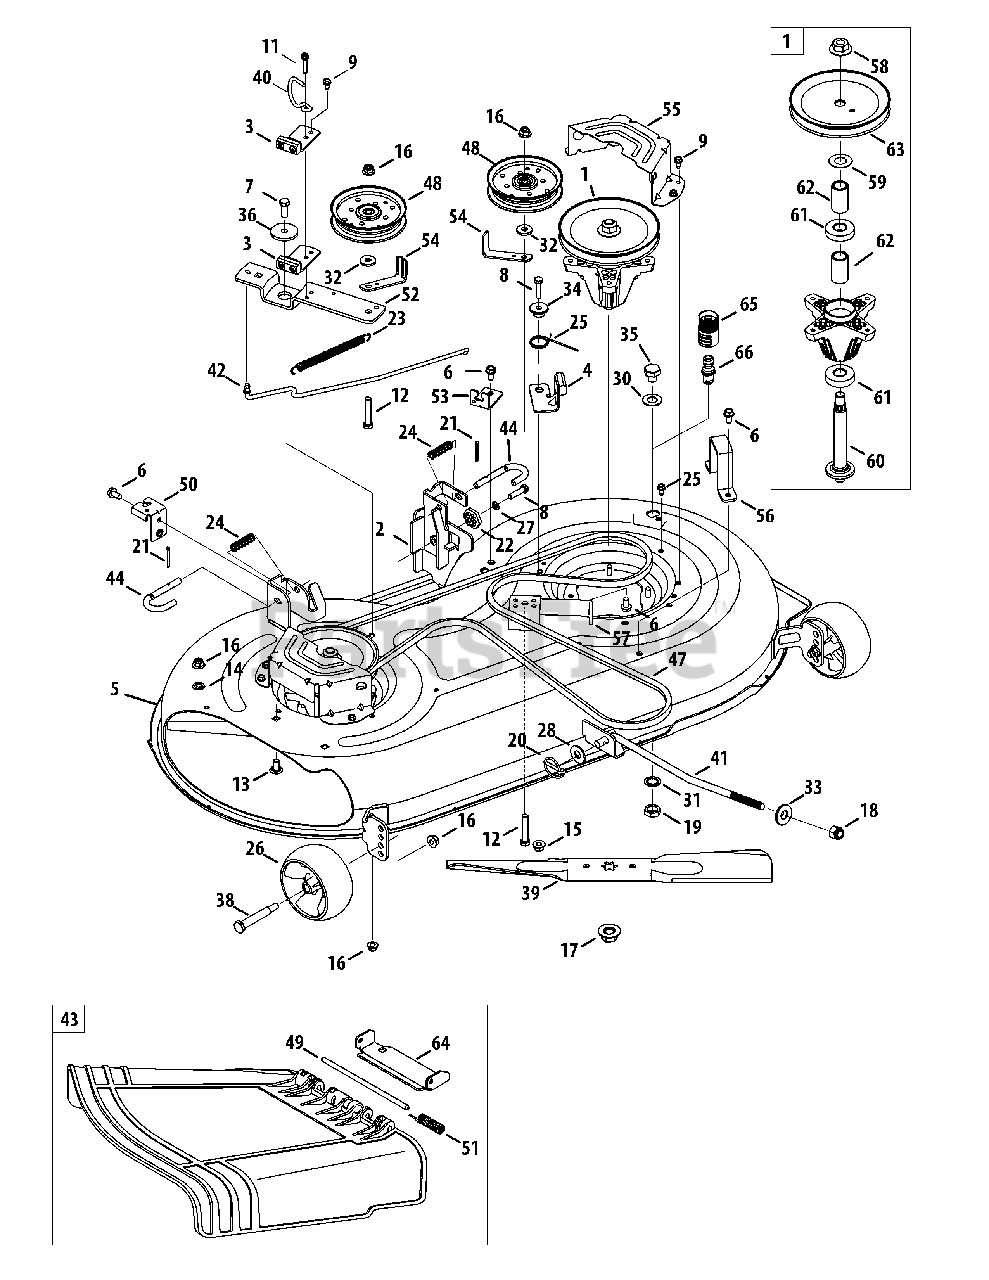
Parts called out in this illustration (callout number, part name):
1	Pulley Spindle Ass’y 6.3 dia.
2	Deck Hanger Bracket Ass'y LH
3	Deck Brake Assembly
4	Deck Brake Assembly
5	Deck Assembly, 42" w/ deck wheels
6	S-Tapp Screw 5/16-18 x .75
7	Hex. Hd. Cap Screw. 3/8-16 x 1.0 Gr. 5
8	Hex Wash Tap Screw 5/16-18 x 1.25
9	Hex Wash S-Tapp Screw 1/4-20 x .50
11	Hex Bolt 1/4-20 x 1.25
12	Hex. Hd. Cap Screw. 3/8-16 x 2.0 Gr. 5
13	Car riage Bolt 3/8-16 x .75 Gr. 1
14	Push Nut, 3/8
15	Hex Flange Locknut 5/16-18 Gr. F, Nylon
16	Hex Flange Locknut 3/8-16 Gr. F Nylon
17	Hex Flange Locknut 5/8-18
18	Hex Locknut 1/2-13
19	Hex Nut M16-1.5 DIN 936
20	Lynch Pin
21	Cotter Pin 1/8 x 1.25
22	Deck Gear Ad juster
23	Extension Spring .62 dia. x 6.12 Lg.
24	Comp. Spring .535 OD x 1.751
25	Torsion Spring .992 ID x 1.17 OD
26	Deck Wheel 5.0 Dia.
27	L-Wash 5/16 ID
28	Flat Washer .531 ID x 1.25 OD x .10
30	Flat Washer .640 ID x 1.24 OD x .06
31	L-Washer Internal
32	Flat Washer .385 ID x .870 OD x .092
33	Cupped Washer .63 x 1.25 x .18
34	Shoulder Spacer .5 x .145
35	Screw Plug M16 x 1.50
36	Shoulder Spacer .8540 x .200
38	Shoulder Bolt .496 x 2.5, 3/8-16
39	Blade, 21.23", 2-in-1
40	Belt Keeper Rod
41	Front Lift Deck Rod
42	Brake Control Rod
43	Side Discharge Chute Assembly
44	Handle Rod .375
47	V-Belt
48	Idler Pulley w/Flange 4.25 Dia
49	Hinge Pin .3125 diam. x 7.96" Lg.
51	Torsion Spring .44 ID x 2.0
52	Idler Pivot Bracket
53	Deck Cable Engagement Bracket
54	Belt Guard Pulley Bracket
55	Belt Cover
56	Deck Stop
57	Deck Support Stationary Idler Brkt.
58	Hex Flange Locknut 5/8-18
59	Flat Washer .760 ID x 1.5 OD
60	Spindle Shaft 6.11" Lg.
61	Ball Bear ing .787 ID x 1.85 OD x .551
62	Spacer .792 x 1.060 x 1.860
63	Deck Pulley 6.3 dia.
64	Chute Bracket
65	Water Nozzle Adapter
66	Deck Water Nozzle
